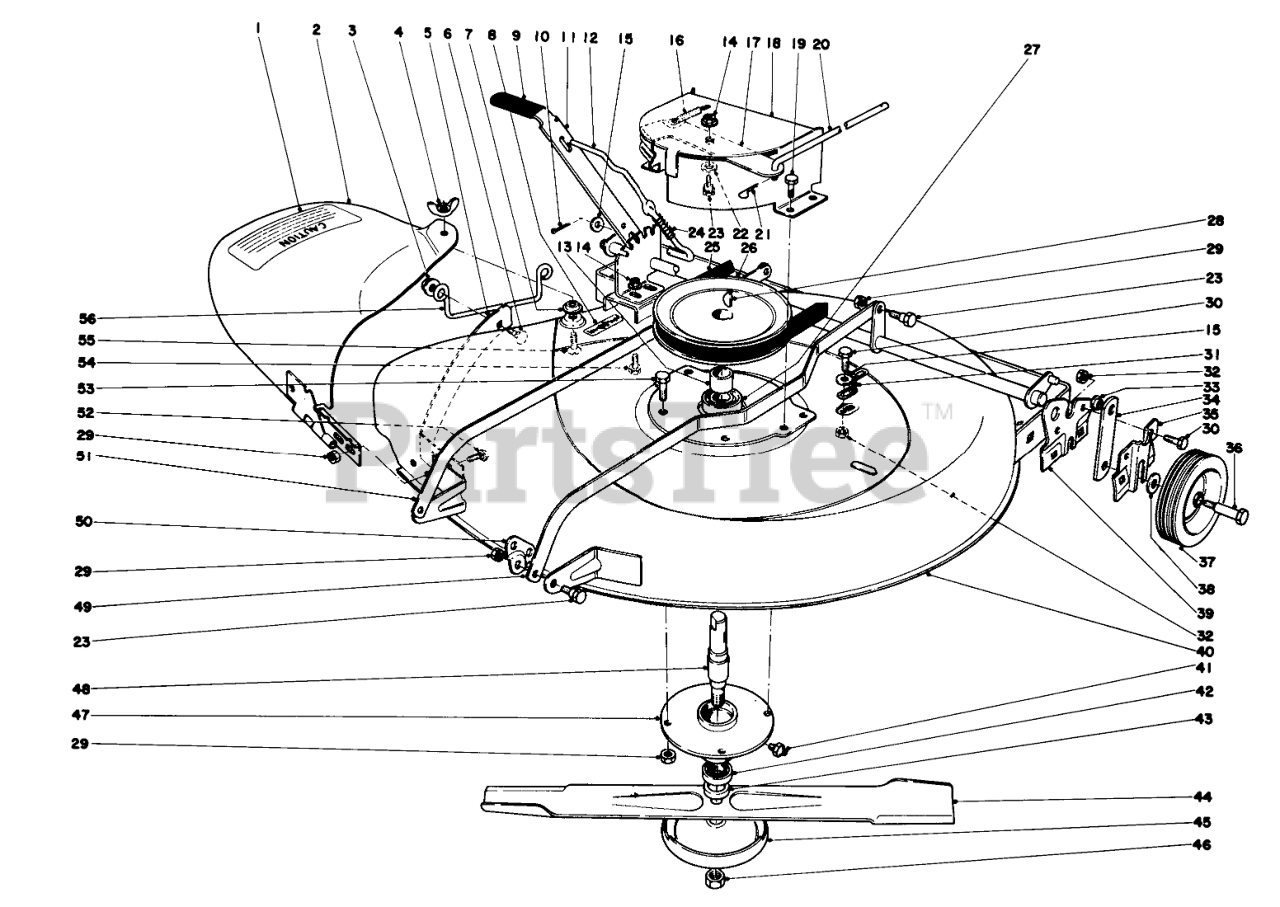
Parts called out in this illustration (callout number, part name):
1	Decal
2	Deflector
3	NUT-LOCK, HHF
4	Wing Nut
5	Bar-Deflector
6	SCREW-CARRIAGE
7	PAL NUT
8	Decal Height of Cut
9	Grip Handle
10	PIN-COTTER
11	Height Adjustment Shaft Assembly
12	Latch Slide
13	Spacer Blade Spindle
14	NUT-HF
15	WASHER-FLAT
16	Spring Blade Brake
17	Lever Blade-Brake
18	Guard Belt
19	SCREW-HWH
20	Rod-Blade Brake
21	PIN-COTTER
22	Washer Thrust
23	Screw
24	Spring
25	V-Belt
26	Pulley
27	Bearing
28	KEY-WOODRUFF
29	NUT-LOCK, CONE
30	SCREW-HH
31	Chain
32	NUT-LOCK, CONE
33	Bushing
34	Slide Height Adj .
35	Retainer, Height Adj.
36	Screw
37	Wheel
38	Washer
39	Bracket R. H.
40	Housing
41	FITTING-GREASE
42	.6693 RP BALL BEARING
43	Spacer
44	Blade
45	Cup
46	NUT-LOCK, CONE
47	MOWER SPINDLE HOUSING
48	Blade Spindle
49	Bar-Parallel L.H.
50	Blade Housing Pivot
51	Battery
52	SCREW-CARR
53	SCREW-HH
54	SCREW-HH
55	5/16-18X7/8 FLT HD MS
56	Bracket Foot Guard
